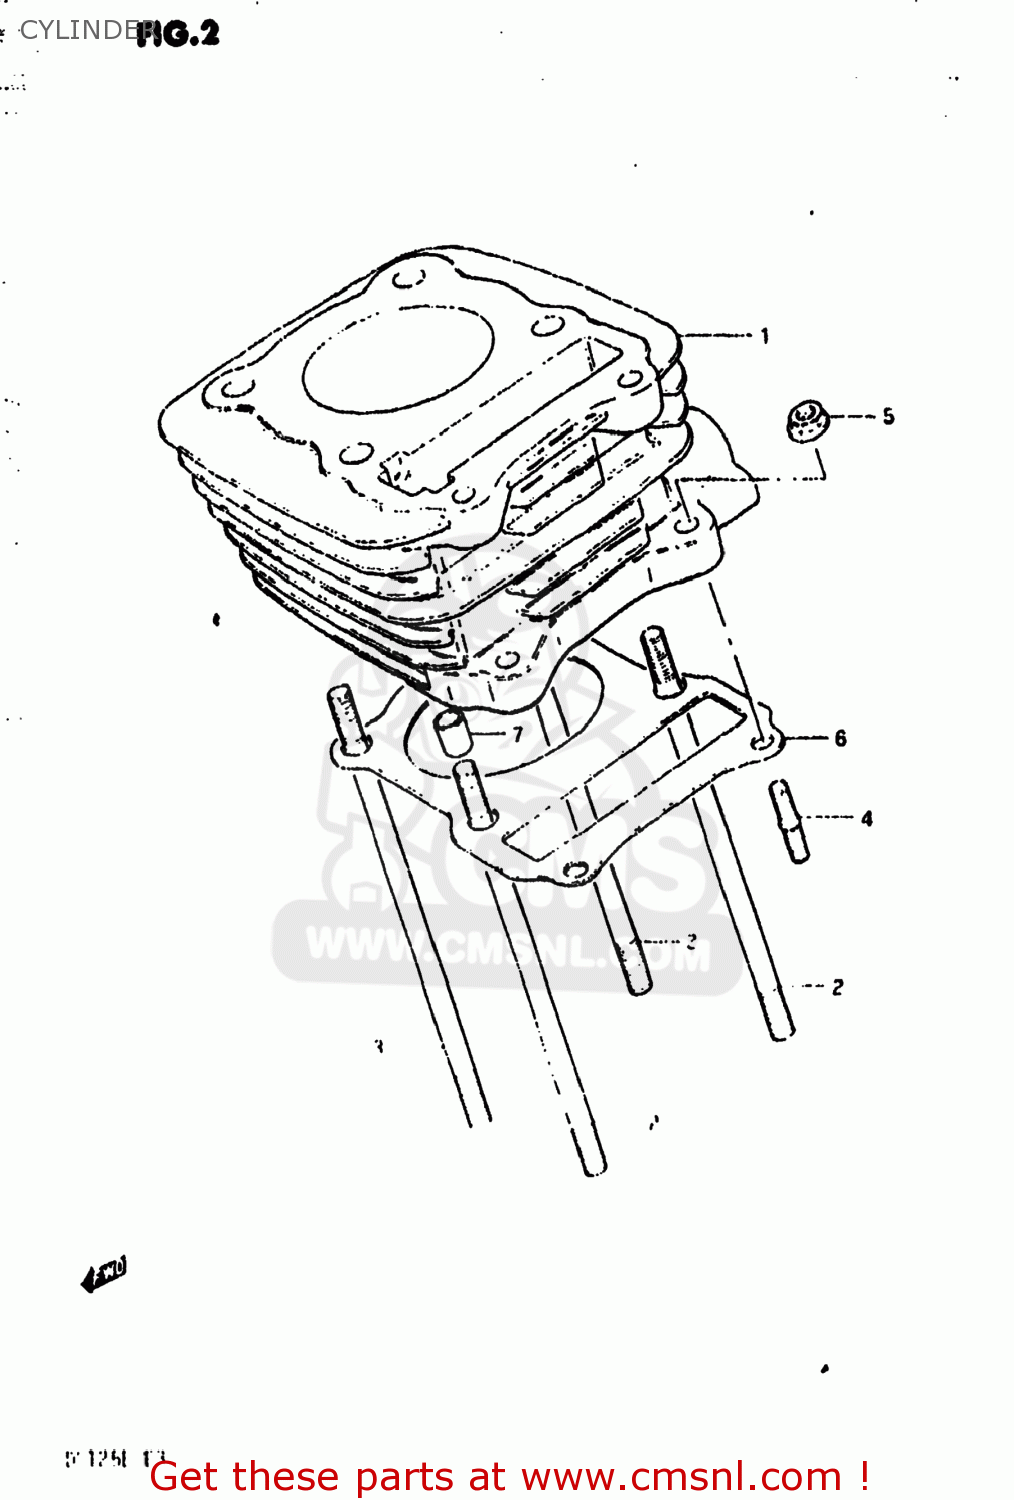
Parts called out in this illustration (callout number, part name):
1	CYLINDER
2	BOLT,STUD
3	BOLT,STUD
4	STUD 6X25
5	NUT
6	GASKET,CYLINDER (MCA)
7	PIN
